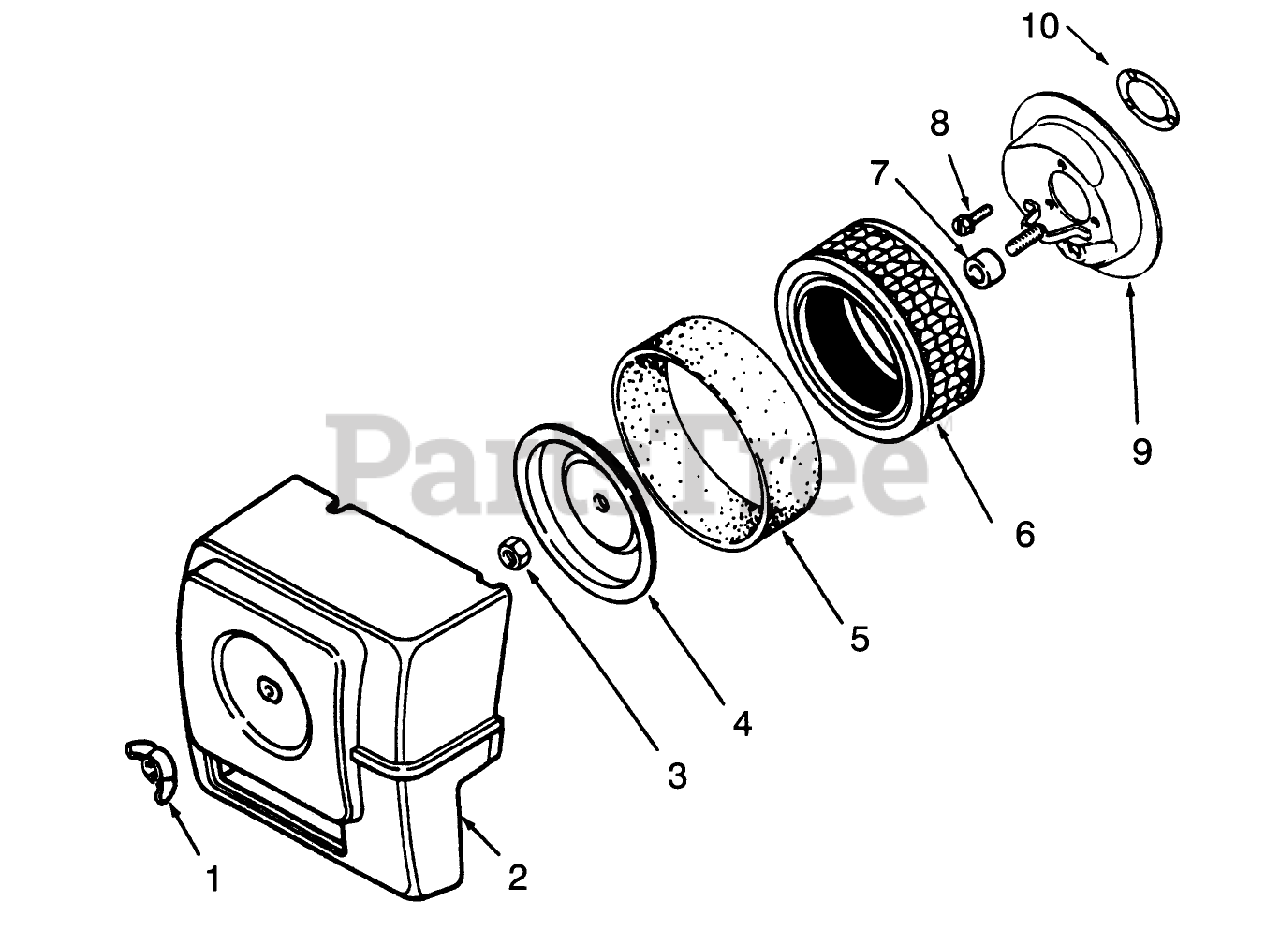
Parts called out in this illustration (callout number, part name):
1	KOHLER X-276-7
2	KOHLER 47-096-10
3	KOHLER 41-100-04
4	KOHLER 52-082-04
5	KOHLER45-083-01
6	KOHLER 45-083-02
7	KOHLER 231032
8	KOHLER X-67-65
9	KOHLER 47-094-20
10	KOHLER 45-041-07
